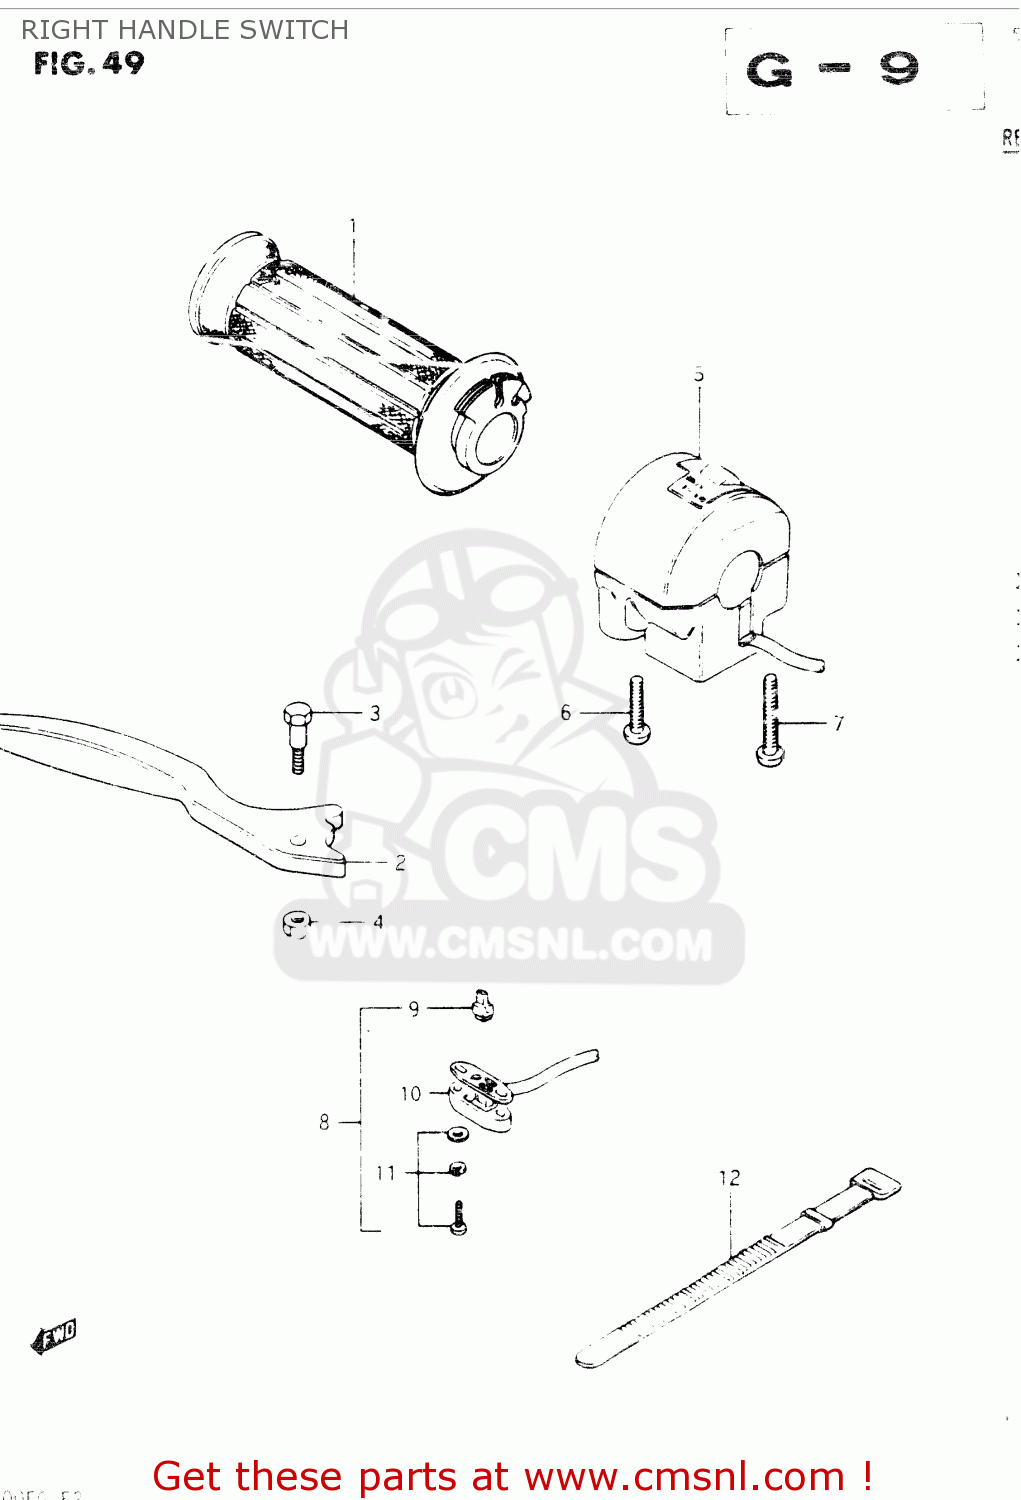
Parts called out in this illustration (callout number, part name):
1	GRIP,THROTTLE
2	LEVER,BRAKE
3	BOLT,LEVER PIVOT
4	NUT
5	SWITCH ASSY, HANDLE LH
6	SCREW
7	SCREW
8	SWITCH ASSY,STOP
9	CONTACT,SWITCH
10	COVER,FR BK TERMINAL BASE
11	SCREW
12	CLAMP(L:120)
